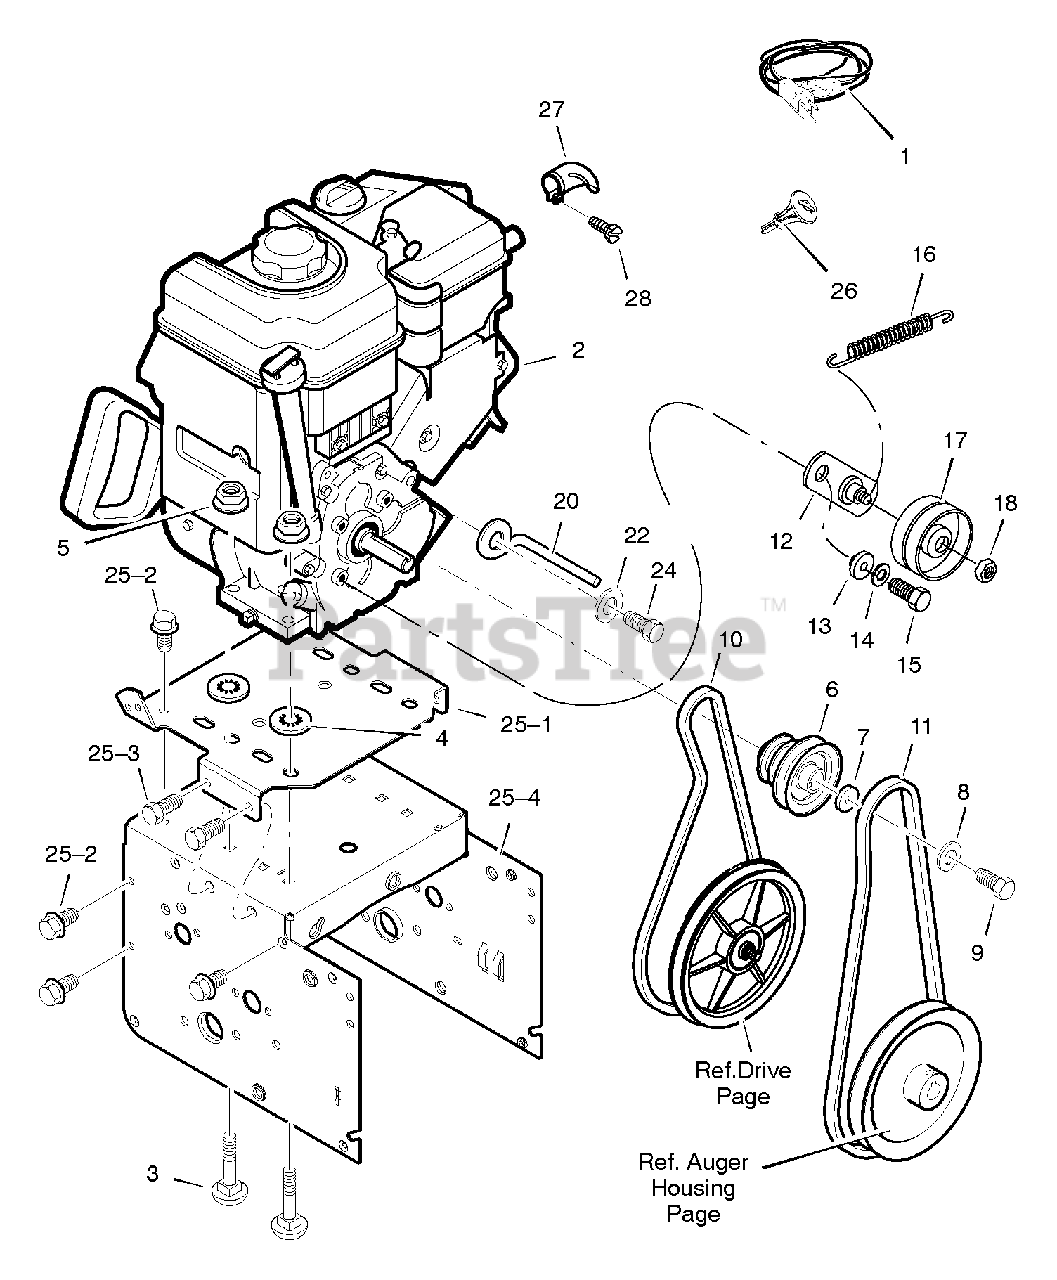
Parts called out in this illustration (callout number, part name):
1	CORD, Electric, 10FT. 110V
2	ENGINE
3	BOLT, CARRIAGE
4	RETAINER, PUSH
6	PULLEY, ENGINE
7	WASHER
8	WASHER
9	SCREW
10	BELT, DRIVE V 3L
11	BELT, AUGER V 4L
12	BRACKET ASSEMBLY, IDLER
13	BUSHING, IDLER BRACKET
14	WASHER, SPLIT
15	SCREW 5/16-24 X 0.75
16	SPRING, IDLER TRACTION DRIVE
17	PULLEY, IDLER
18	NUT, JAM 3/8-16
20	GUIDE, ROD BELT
22	WASHER
25	FRAME ASSEMBLY
25-1	PLATE, ENGINE
25-2	SCREW
25-4	MOTOR BOX
26	KEY, ENGINE
27	DEFLECTOR, Muffler
